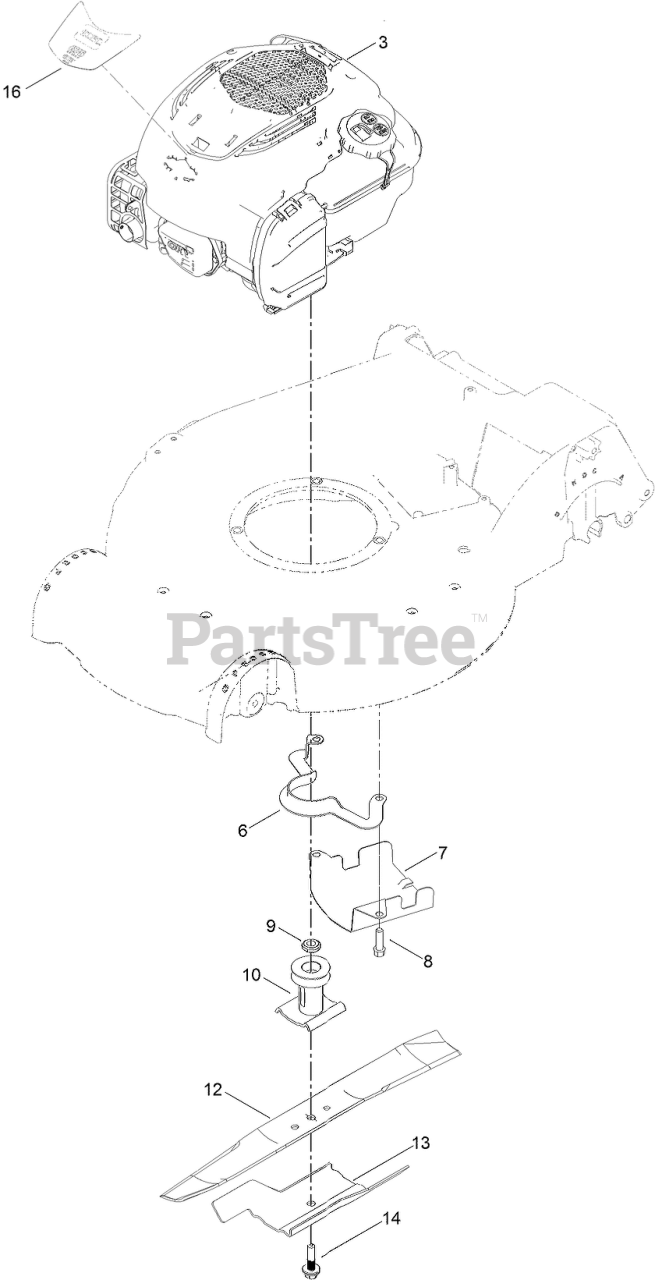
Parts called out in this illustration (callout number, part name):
6	GUIDE-BELT
7	SHIELD-GRASS
8	SCREW-TAPTITE
9	Spacer-Driver
10	DRIVER-BLADE
12	BLADE-RECYCLING
13	Accelerator-Blade
14	BOLT-BLADE
16	DECAL-SHROUD
